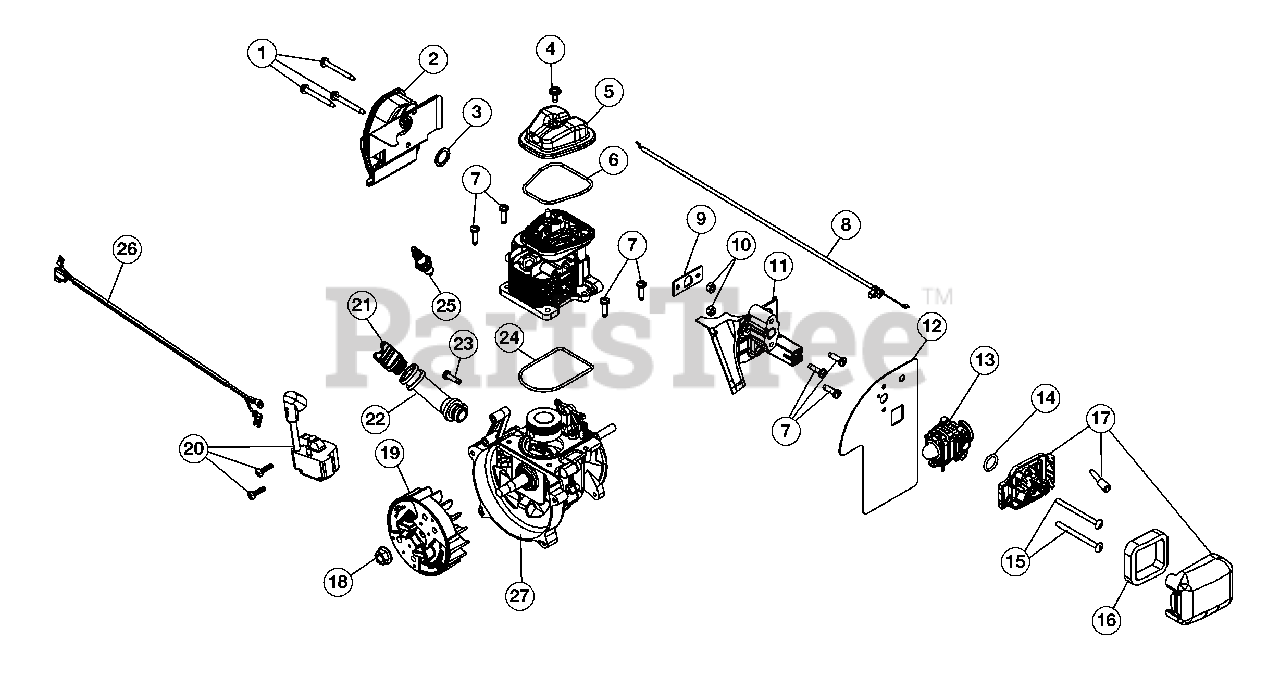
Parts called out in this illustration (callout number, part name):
1	Muffler Screws
2	Muffler Assembly (Incl. 1 & 3)
3	Muffler Gasket
5	Rocker Cover
7	Screw
8	Throttle Cable
9	Insulator Gasket
12	Carburetor Gasket
13	Carburetor
14	Carburetor O-Ring
17	Air Cleaner Assembly (Incl. 16)
19	Flywheel Asssembly
21	Oil Plug
22	Oil Fill Tube (Incl. 23)
25	Spark Plug
